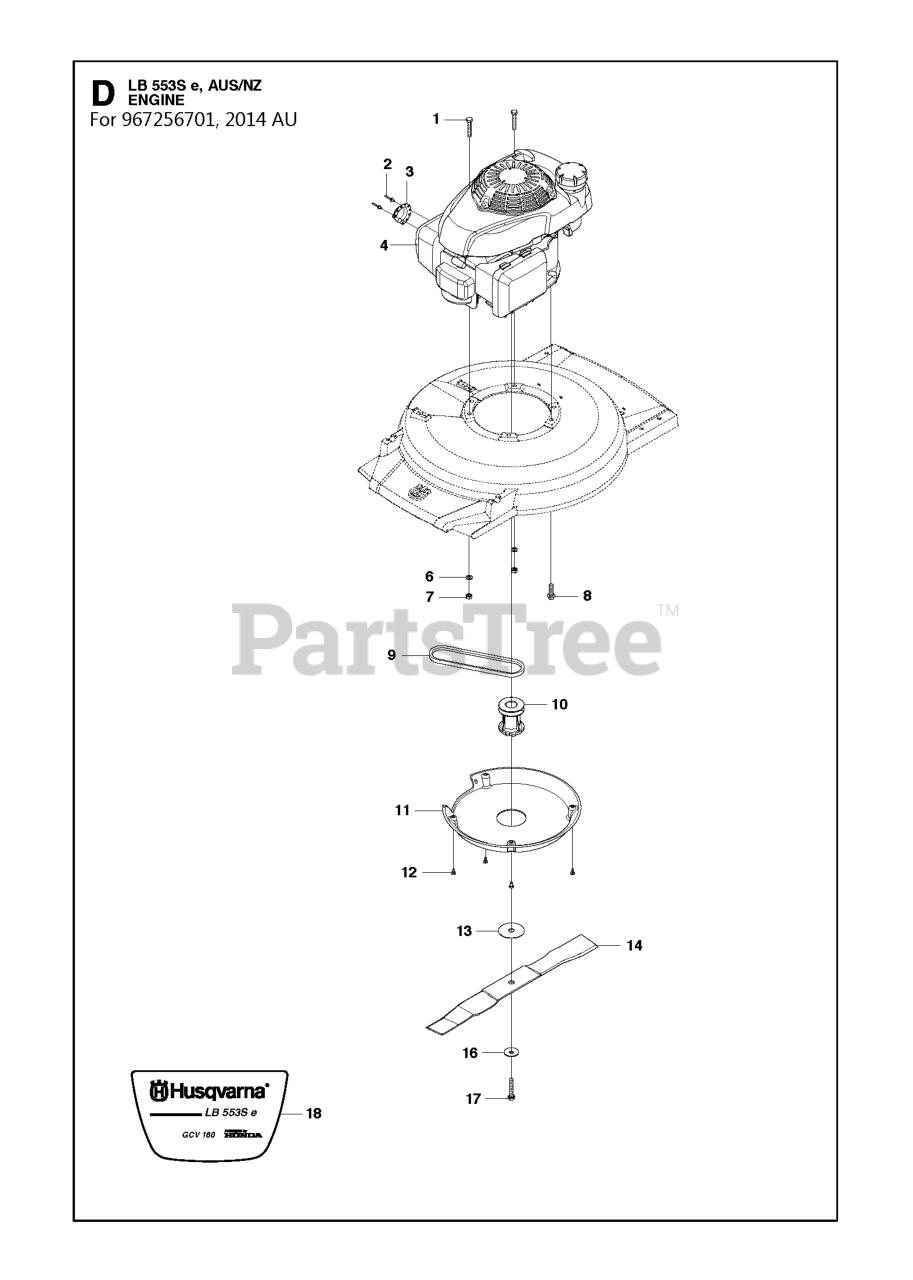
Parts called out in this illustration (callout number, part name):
6	WASHER BRB 8.4X17
7	LOCKNUT M8
12	SCREW ITXPANTT M5X10 ZPB (A00
